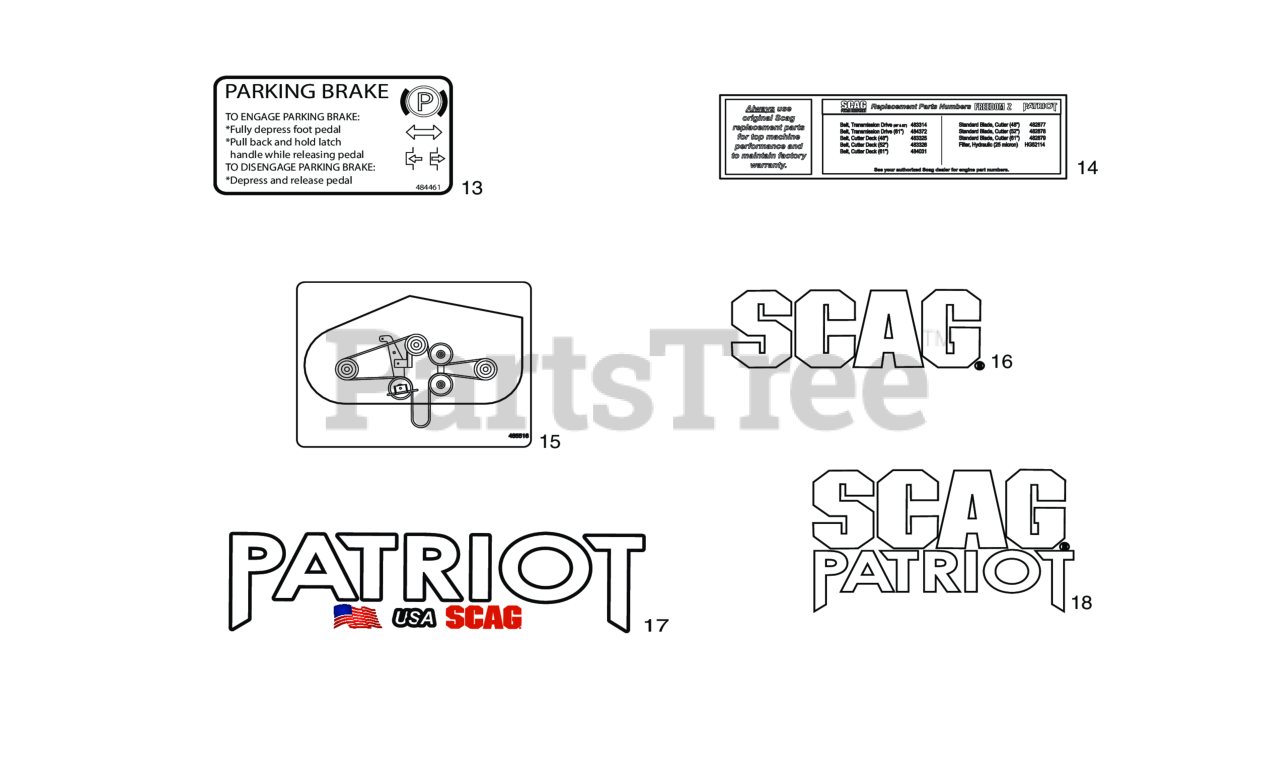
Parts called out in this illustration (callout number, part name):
13	Decal, Brake
14	Decal, SFZ / SPZ Replacement Parts
15	Decal, SZL / SFZ / SPZ Belt Routing
16	Decal, Scag - Fuel Tank
17	Decal, Patriot, (Scag Gold Logo) - Fuel Tank
18	Decal, Scag Patriot, (Scag Gold Logo) - Fuel Tank
